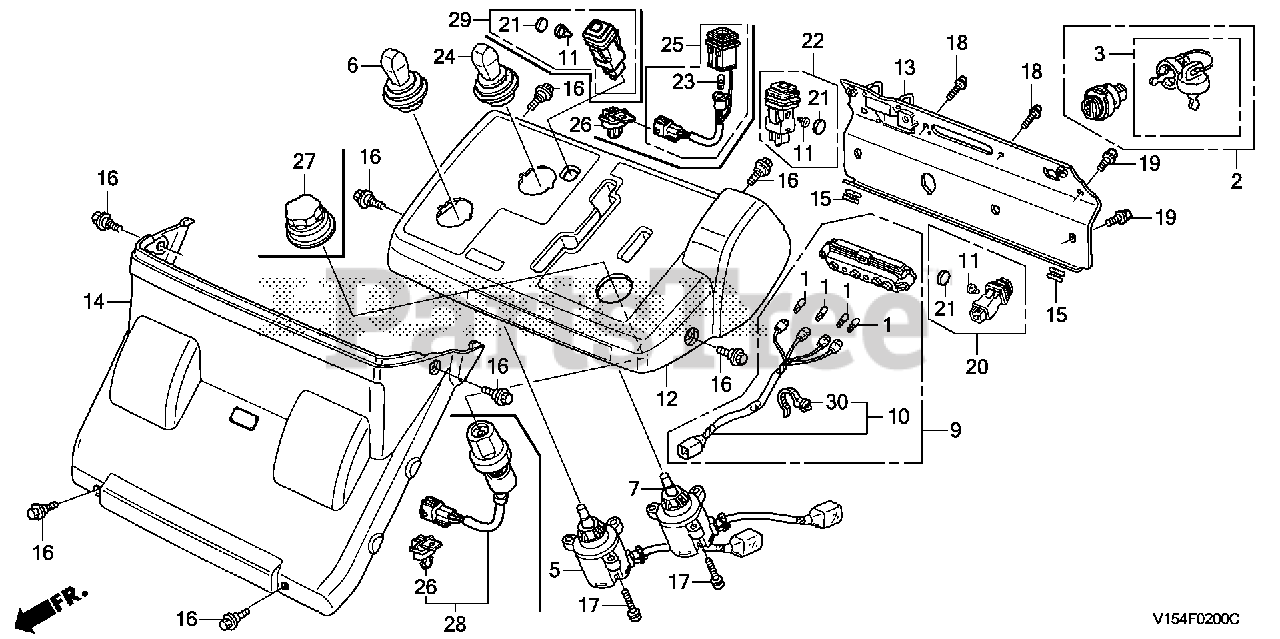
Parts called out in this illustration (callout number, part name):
1	BULB, WEDGE BASE (24V 1.4W)
2	SWITCH ASSY., COMBINATION
3	KEY ASSY., COMBINATION SWITCH
5	SWITCH ASSY., CHUTE CONTROL
6	BOOT, RUBBER (BLACK)
7	SWITCH ASSY., CHUTE CONTROL
9	INDICATOR ASSY., WARNING
11	SOCKET ASSY., LAMP
12	PANEL, CONTROL
13	PANEL, RR.
14	COVER, FR. PANEL *NH296* (ALPS GRAY)
16	BOLT, CONTROL PANEL
17	BOLT-WASHER (5X20)
18	SCREW-WASHER (4X16)
19	BOLT, FLANGE (6X12)
21	CAP, VALVE
23	BULB (28V/2.5W)
24	BOOT, RUBBER (LIGHT GRAY)
25	SWITCH ASSY., CLUTCH ON OPERATING
26	CLIP, CONNECTOR (DARK GREEN)
27	KNOB, MODE SELECT
28	SWITCH ASSY., MODE SELECT
29	SWITCH ASSY., CLUTCH ON OPERATING
30	BAND, WIRE HARNESS (110MM) (BROWN)
